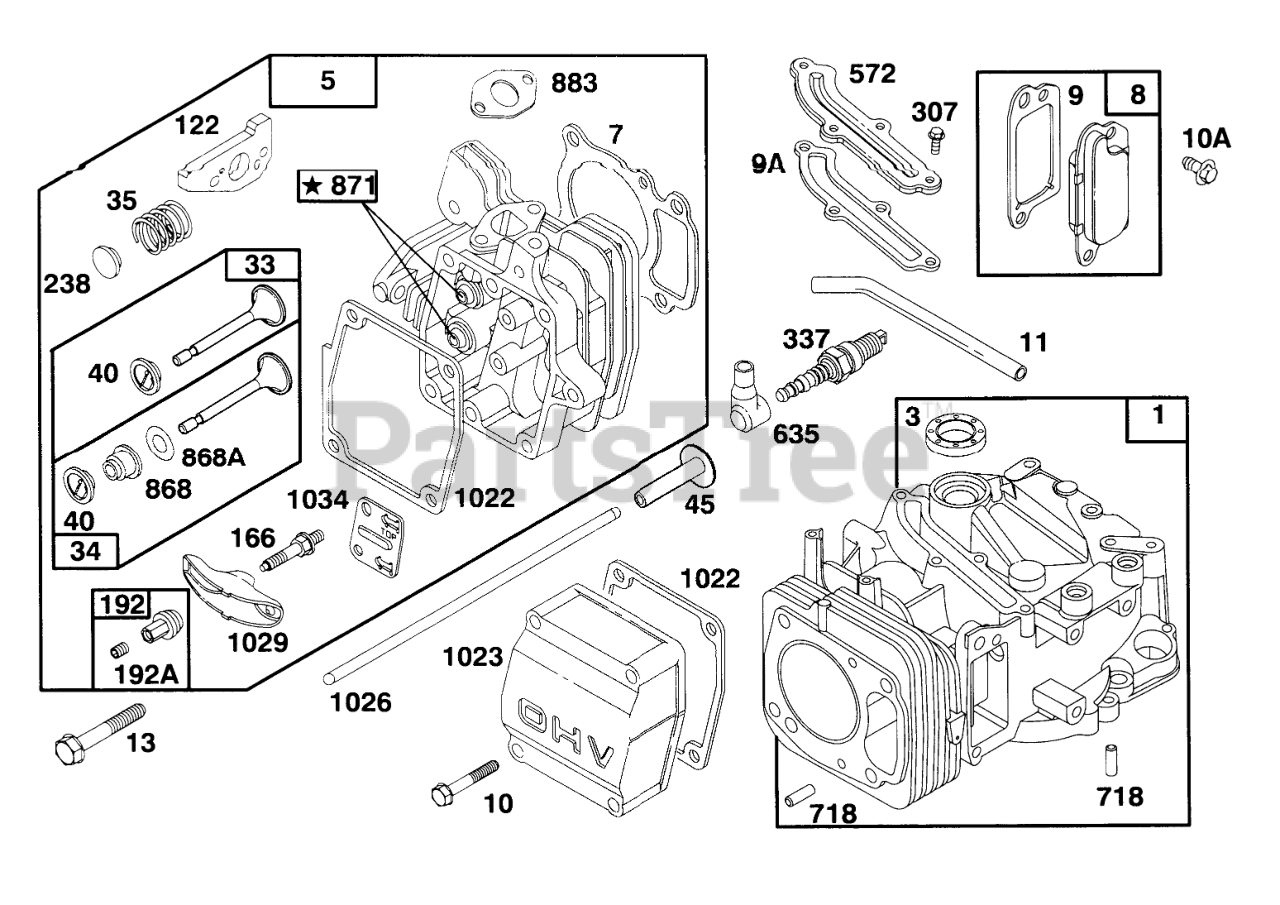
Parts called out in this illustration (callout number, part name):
1	CYLINDER ASSEMBLY
3	SEAL - OIL
5	CYLINDER HEAD
7	CYLINDER HEAD GASKET
8	Breather Assy
9	BREATHER GASKET
9A	GASKET-BREATHER
10	HEX HEAD SCREW
10A	HEX HEAD SCREW
11	TUBE - BREATHER
13	CYLINDER HEAD SCREW
33	EXHAUST VALVE
34	INTAKE VALVE
35	VALVE SPRING
40	SPRING RETAINER
45	VALVE TAPPET
122	ADAPTER ASSEMBLY
166	ROCKER ARM STUD
192	NUT - HEX SPECIAL
192A	SCREW SET
238	VALVE CAP
307	SCREW - SEM
337	PLUG-SPARK
572	BAFFLE - CYCLINDER
635	SPARK PLUG ELBOW
718	DOWEL - SLEEVE
868	SealAssy-Valve
868A	Seal-Valve
871	Bushing-Guide
883	EXHAUST GASKET
1022	ROCKER COVER GASKET
1023	COVER - VALVE
1026	PUSH ROD
1029	ROCKER ARM
1034	PUSH ROD GUIDE
